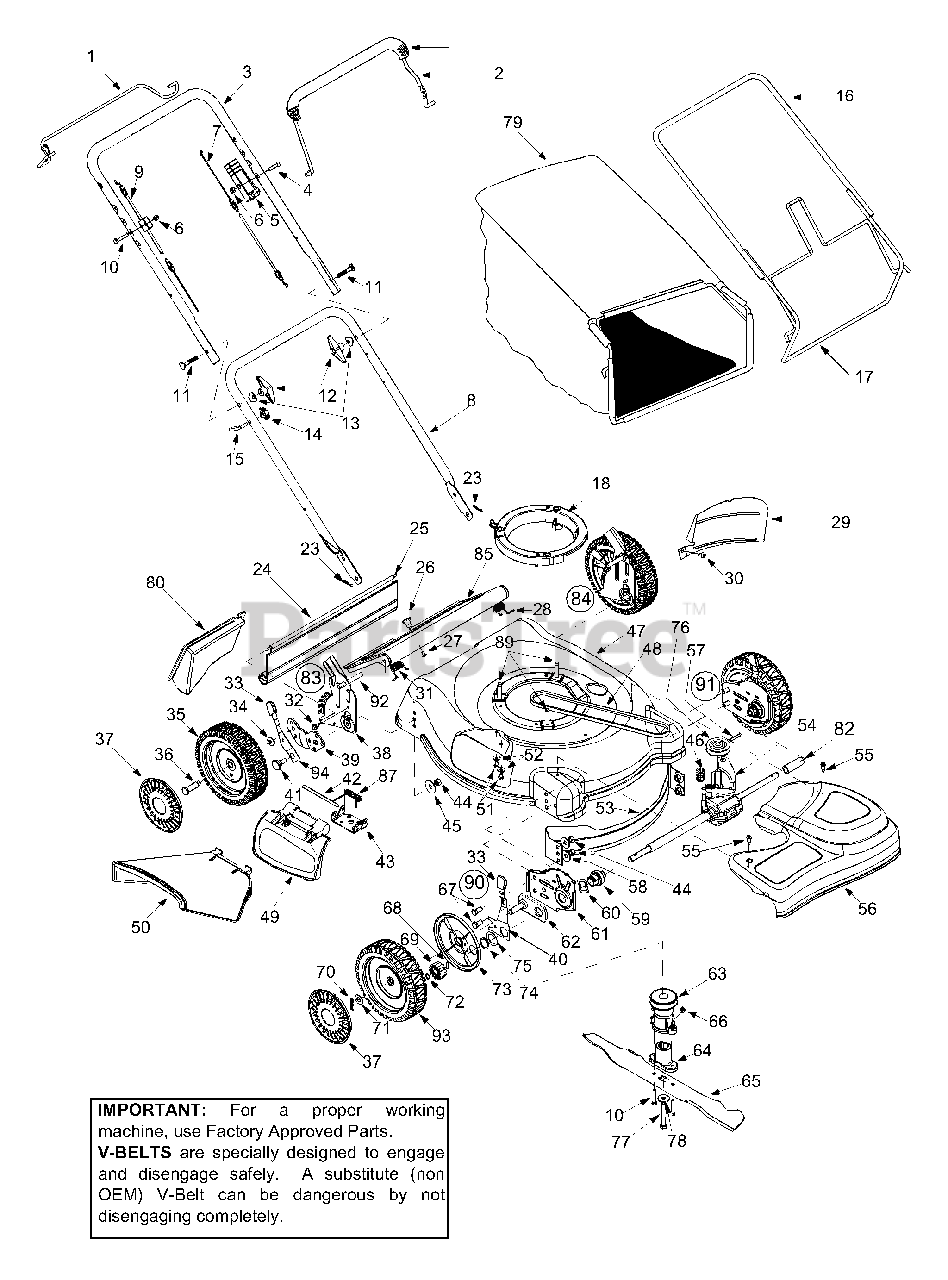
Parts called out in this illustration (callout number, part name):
5	Control Housing
6	Hex Lock Nut 1/4-20
7	Control Cable: 43"
9	Drive Cable
10	Hex Screw 1/4-20 x 1.5"
11	Carriage Bolt
12	Handle Knob
13	Saddle Washer
14	Wing Nut
15	Rope Guide
23	Hairpin Clip
24	Rear Trail Shield
25	Wire: Trail Shield
27	Scr. Tr. Mach. #10-24 x 0.380"
28	Torsion Spring LH
30	Scr. AB 1/4-14 x 0.625"
31	Torsion Spring RH
32	Hex Scr. w/ Wash. 1/4-14 x 0.62"
33	Knob
34	Bell Washer .375 x .870
35	Wheel: Rear
36	Shoulder Screw
37	Hubcap
38	Handle Bracket Assembly LH
39	Pivot Bar LH
40	Front Lever RH
41	Shoulder Screw
42	Hinge Pin
44	Hex Nut
45	Flat Washer
46	Belt Tension Spring
49	Mulch Plug
50	Discharge Deflector SD
51	TT Screw 1/4-20 x 0.5"
52	Bell Washer 0.265" x 0.75"
55	Screw #12 x 0.457"
56	Front Drive Cover: Yellow
57	Roll Pin
58	Bell Washer
59	Bearing Support
60	Wave Washer
62	Pivot Plate Assembly
63	Drive Pulley
64	Blade Adapter
65	Mulching Blade w/ Star: 21"
66	Hex Lock Nut
67	Hex Screw
68	Dowel Pin
69	Gear 14T RH
70	Hairpin Clip
71	Flat Washer
72	Snap Ring
73	Wheel Dust Cap
74	Snap Ring
75	Washer DD 1.5" O.D.
76	Input Pulley
77	Hex Bolt
78	Bell Washer
79	Grass Bag
82	Slev. Spacer LH
83	Height Adj. Assembly RH Compl.
84	Height Adj. Assembly LH Compl.
87	Torsion Spring
89	TT Screw
90	Height Adj. Assembly RH Compl.
91	Height Adj. Assembly LH Compl.
92	Weld Pin
93	Wheel: Front
94	Spring Lever
